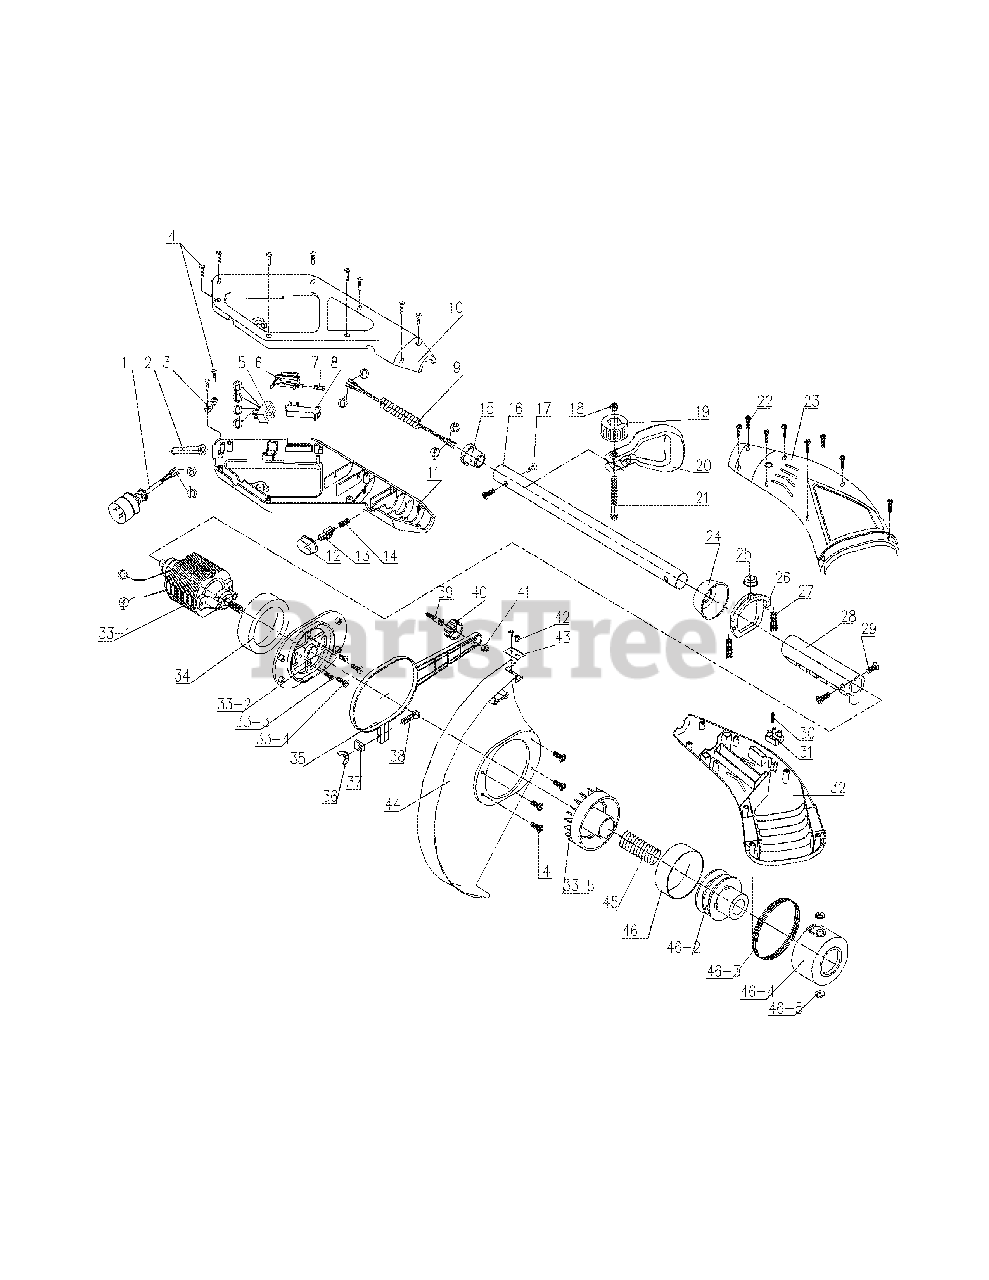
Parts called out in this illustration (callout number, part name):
1	POWER CORD
2	CORD GUARD
3	PLATE (PRESSING CORD)
10	UPPER HANDGRIP (R)-MTD RED
11	UPPER HANDGRIP (L)-MTD RED
12	BUTTON-Black
15	JOINT PIPE
16	CENTRAL TUBE
20	CENTRAL HANDGRIP
23	HOUSING (R)-MTD RED
25	BUTTON-Black
26	FIXED RING
28	EXPANDING RING
31	TERMINAL BLOCK
32	HOUSING (L)-MTD RED
33-5	WHEEL PLATE
34	CUSHION RING
35	CUSHION RING
43	WIRE CUTTING BLADE
46-1	BLISTER PACK
46-2	SPOOL CARRIER
46-3	WIRE-CUTTING
46-4	SPOOL COVER
